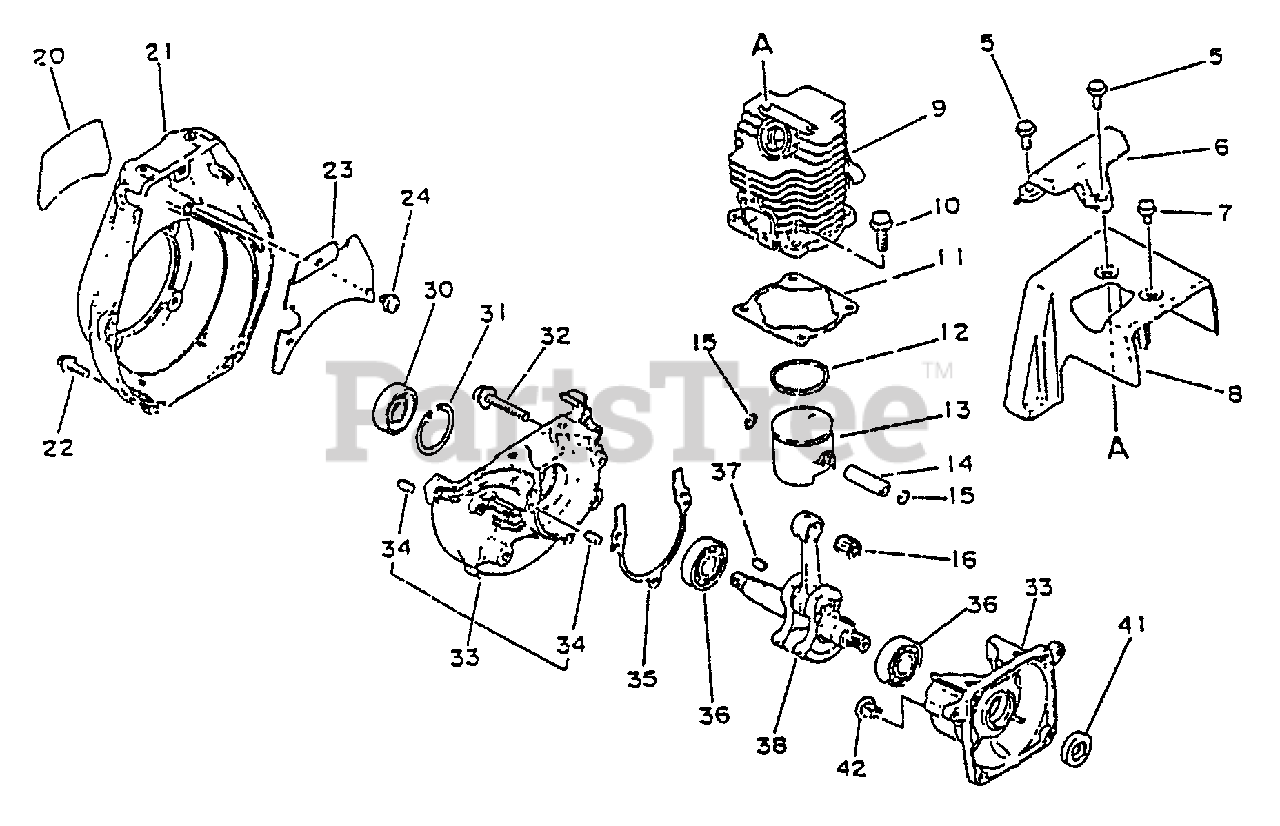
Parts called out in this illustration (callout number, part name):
5	SCREW - 4X14
6	GUARD - TOP
7	SCREW - 4X10
8	COVER, ENGINE
9	CYLINDER
10	SCREW - 5X16
11	GASKET, CYLINDER
12	RING, PISTON
13	PISTON
14	PIN, PISTON
15	RING, RETAINING
16	BEARING, NEEDLE
20	LABEL - MODEL
21	CASE, FAN
22	SCREW - 4X16
23	SHIELD, FAN
24	SCREW - 4X8
30	SEAL, OIL - 12
31	RING, RETAINING - 28
32	SCREW - 5X28
33	CRANKCASE KIT
34	PIN - LOCATING
35	GASKET, CRANKCASE
36	BEARING, BALL - 6001C3
38	CRANKSHAFT ASSY
41	SEAL, OIL
